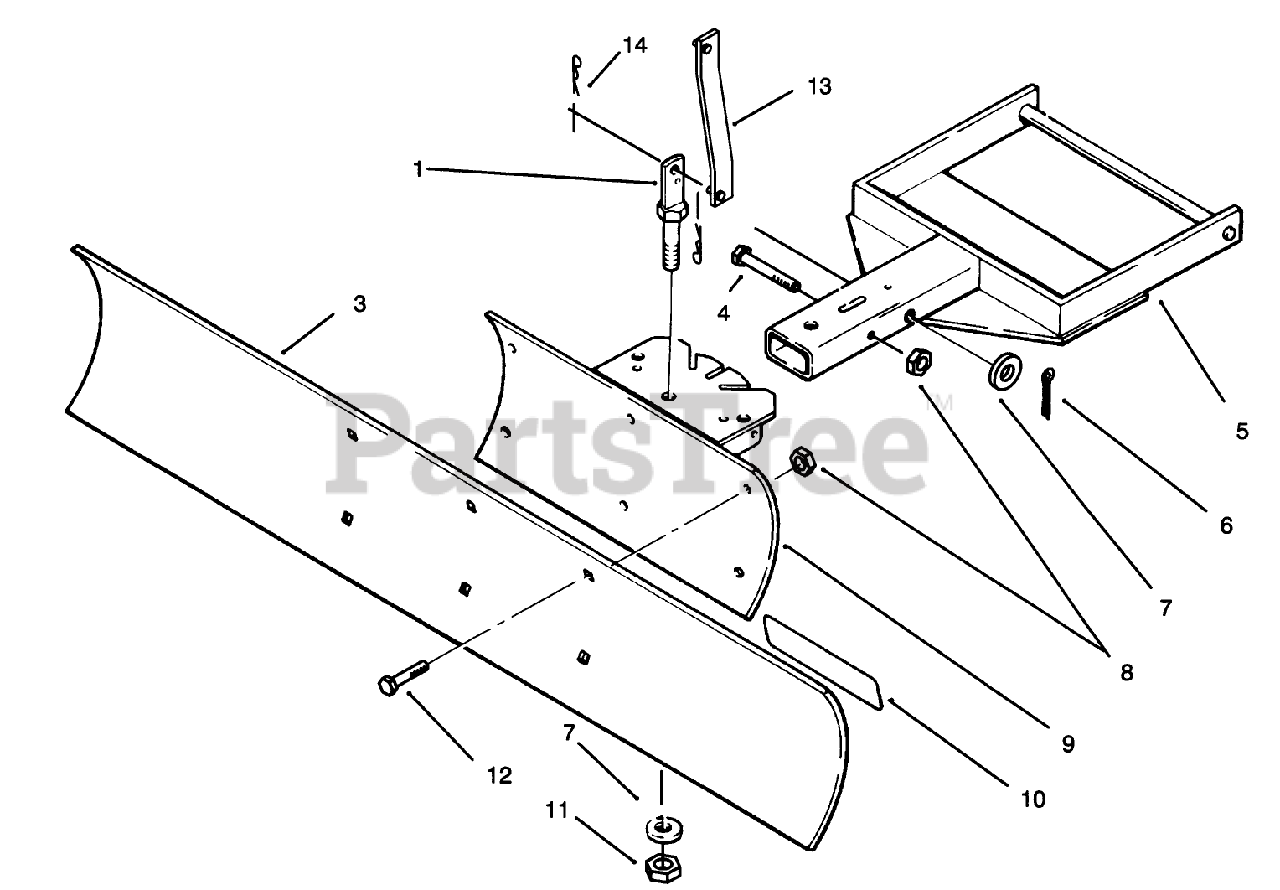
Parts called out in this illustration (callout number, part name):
1	Wa-Scrw
4	SCREW-HH
5	ASS'Y-FRAME *R
6	PIN-COTTER
7	WASHER-FLAT
8	NUT-LOCK, NI
9	ASS'Y-QUADRANT
12	BOLT-CARR
14	Hairpin
